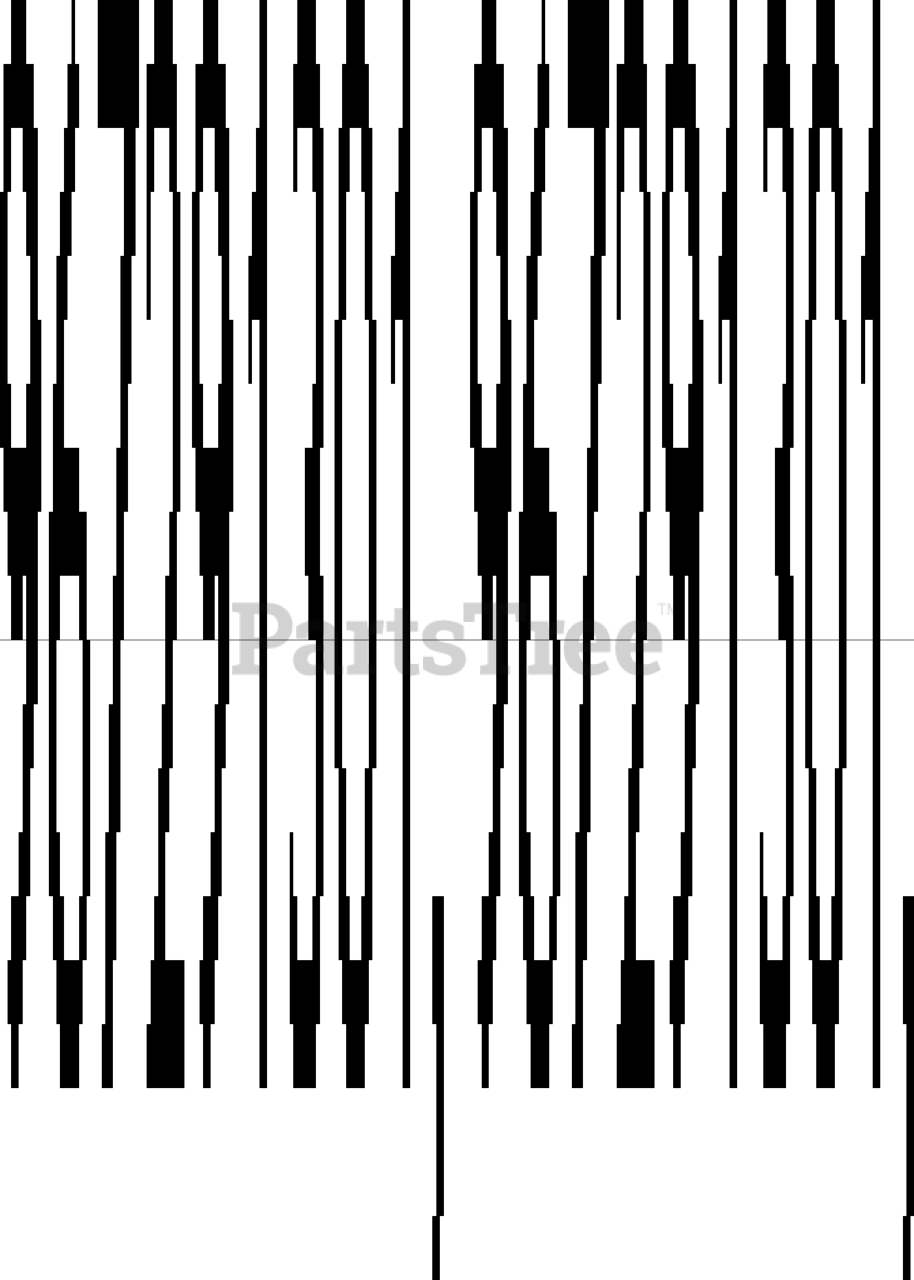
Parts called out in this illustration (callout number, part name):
2	SPRING BRACKET
5	STEERING WHEEL
7	NUT
9	SPACER
10	NUT
11	BRACKET STEERING ASSY WITH BUS
12	BRACKET STEERING ROD ASSY
13	RETAINING RING SGA 15
16	PROTECTIVE COVER
20	COLLAR SCREW
22	WIRE ASSY
25	RETAINING RING
26	STEERING CHAIN
28	WIRE GUIDE
31	Ball Bearing 6005-2rs
32	BALL BEARING 6010 2RS1
33	CIRCLIP SGH 47
34	RETAINING RING SGA 25
